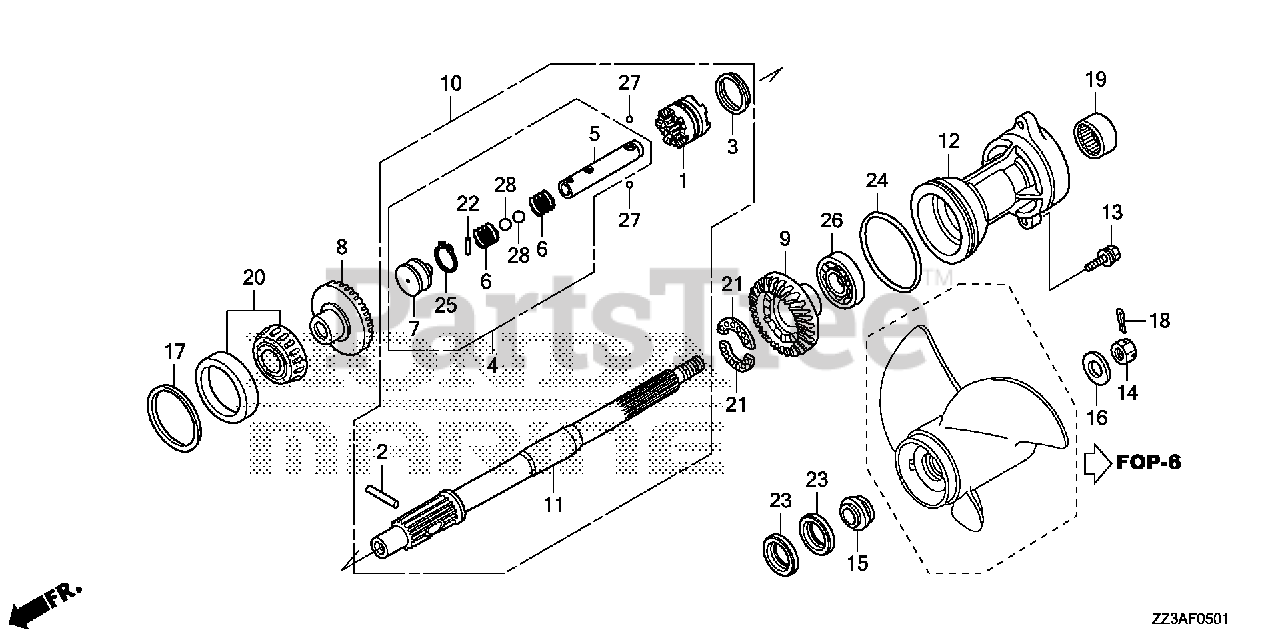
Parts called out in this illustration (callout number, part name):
1	SHIFTER, CLUTCH (POWER THRUST)
2	PIN, SHIFTER (8X47)
3	RING, CROSS PIN
4	SLIDER, SHIFT (POWER THRUST)
5	SLIDER, SHIFT (POWER THRUST)
6	SPRING, SHIFT (POWER THRUST)
7	PLATE, SHIFT
8	GEAR, FR. BEVEL (28T) (POWER THRUST)
9	GEAR, RR. BEVEL (28T) (POWER THRUST)
10	SHAFT ASSY., PROPELLER (POWER THRUST)
11	SHAFT, PROPELLER (POWER THRUST)
12	HOLDER, PROPELLER SHAFT *NHB14M* (AQUA MARINE SILVER METALLIC)
13	BOLT-WASHER (10X40)
14	NUT, CASTLE (18MM)
15	WASHER, PROPELLER THRUST
16	WASHER, PLAIN (18.5MM)
17	SHIM A, BEVEL (0.10) (FR)
17	SHIM B, BEVEL (0.15) (FR)
17	SHIM C, BEVEL (0.30) (FR)
17	SHIM D, BEVEL (0.50) (FR)
18	PIN, SPLIT (4.0)
19	BEARING, NEEDLE (30X37X26)
20	BEARING, TAPERED ROLLER (50X82X21.5)
21	BEARING, BALL (28X38X3)
22	ROLLER (3X12.8)
23	SEAL, WATER (30X45X7)
24	O-RING (94X4.1)
25	CIRCLIP, OUTER (14MM)
26	BEARING, RADIAL BALL (6208)
27	BALL, STEEL (#7) (7/32)
28	BALL, STEEL (#11) (11/32)
